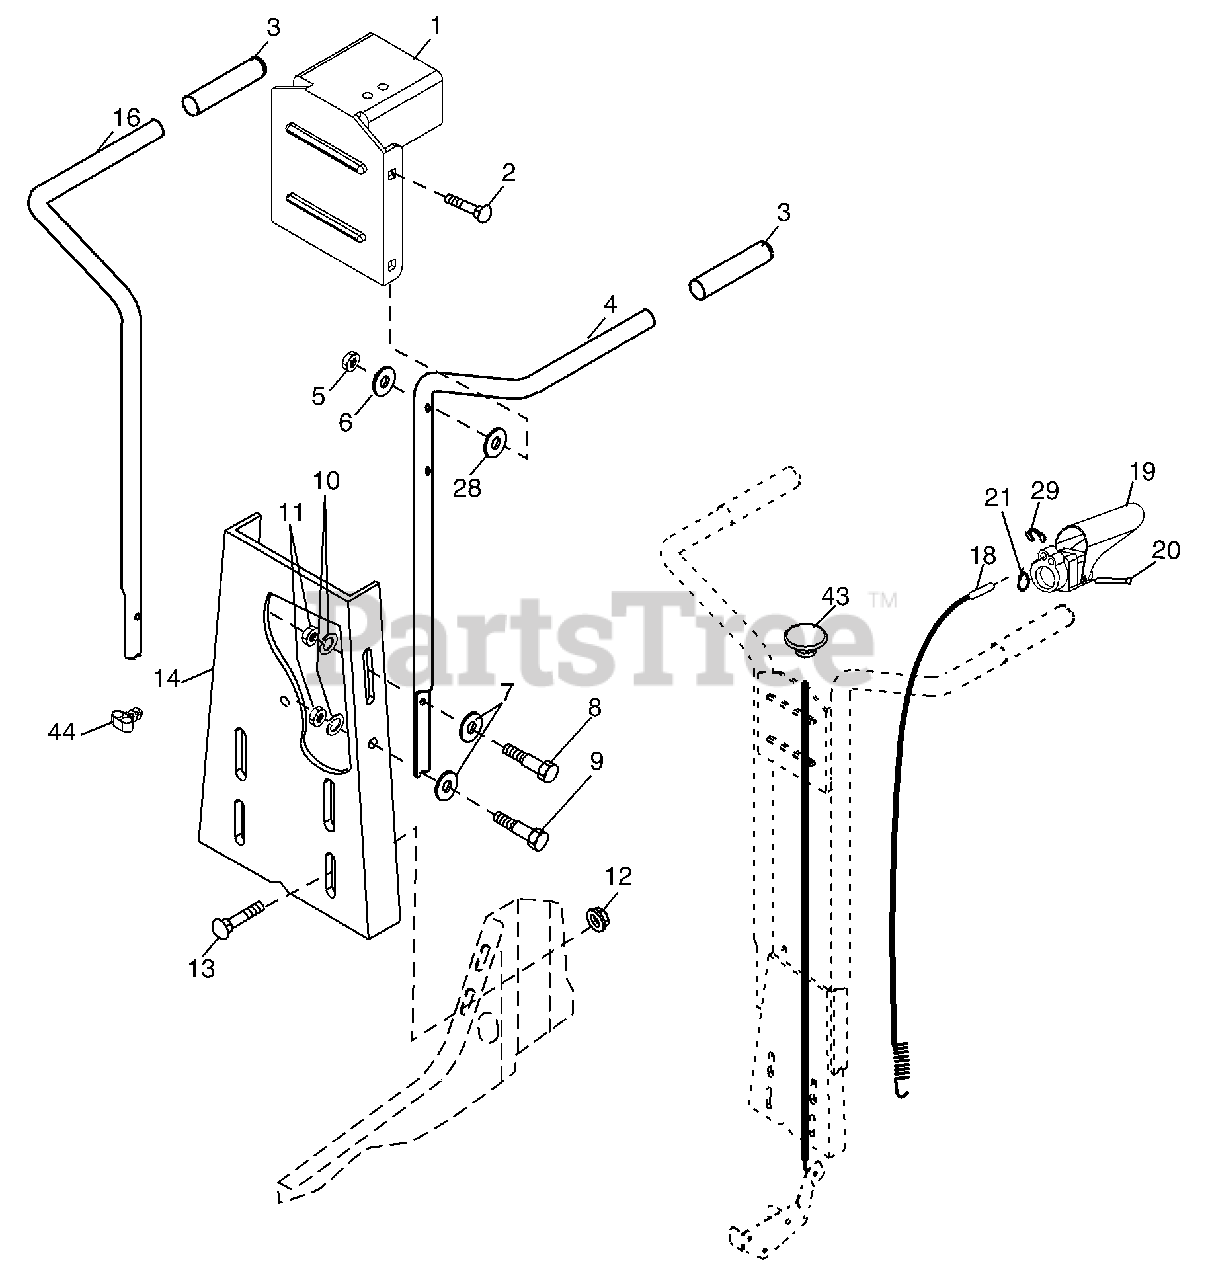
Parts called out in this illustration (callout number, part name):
1	Bracket Handle
2	Bolt, Carriage 5/16-18 unc x 1-1/2
3	Grip, Handle
4	Handle, L.H.
5	Locknut, Crown 5/16-18
6	Washer 11/32 x 11/16 x 16 Ga.
7	Washer 3/8 x 7/8 x 14 Ga.
8	Bolt, Hex Hd. 5/16-18 x 1
9	Bolt, Hex Hd 5/16-18 x 3/4
10	Washer, Lock 5/16
11	Nut, Hex 5/16-18
12	Nut, Flanged 5/16-18
13	Bolt, Carriage 5/16-18 x 3/4 Gr. 5
14	Panel, Handle
16	Handle, R.H.
18	Cable, Control, Tine
19	Lever, Control, Tine
20	Pin, Pivot
21	Ring, Klip
28	Washer 13/32 x 13/16 x 12 Ga.
29	Retaining, Ring
43	Cable Assembly, Reverse
44	Clip
